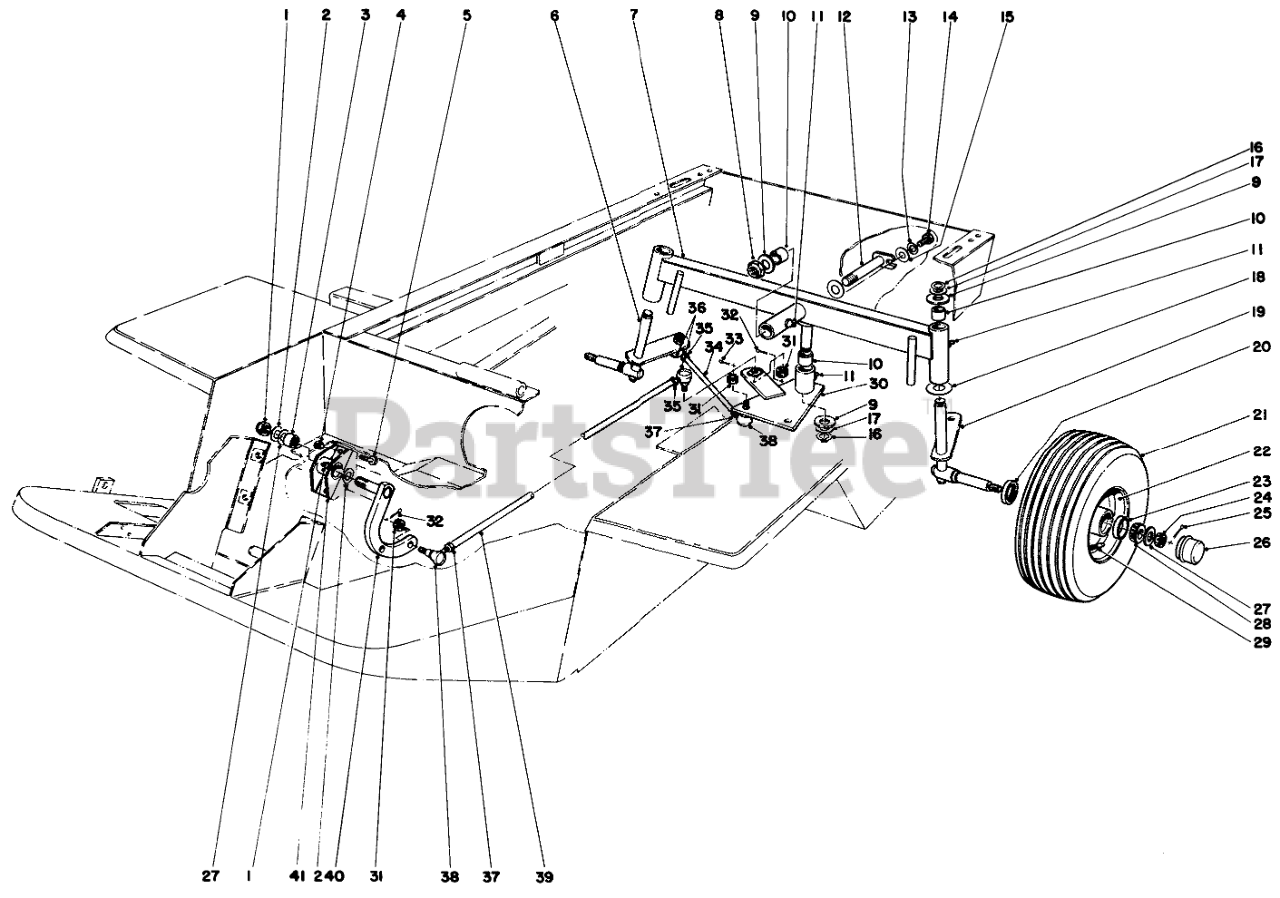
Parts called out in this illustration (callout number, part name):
1	NUT-LOCK, NI
2	THRUST WASHER
3	BEARING-NEEDLE
4	NUT-LOCK, NI
5	SCREW-HH
6	Spindle R.H.
7	Rear Axle (Incl. Ref. #10 & 11)
8	NUT-LOCK, NI
9	WASHER-THRUST
10	BUSHING
11	FITTING-GREASE
12	Pin-RearAxle
13	WASHER-LOCK
14	SCREW-HH
15	WASHER-FLAT
16	RING-RETAINING
17	WASHER
18	WASHER-THRUST
19	Spindle L.H.
21	TIRE 4 PLY
22	Rim (Incl. Ref.#23)
23	BEARING-CUP, TAPERED
24	NUT-HEX, SLOTTED
25	PIN-COTTER
26	CAP-DUST
27	WASHER-FLAT
28	BEARING-CONE, TAPERED
29	VALVE STEM AND CAP ASM
30	Steering Plate (Incl. Ref. #10 & 11)
31	NUT-SLOTTED
32	PIN-COTTER
33	PIN-COTTER
34	STRG TIE ROD R
35	NUT-HJ (LH THREAD)
36	Socket Assembly L.H. (Incl. Ref. #31)
37	NUT-JAM
38	Socket Assembly R.H. (Incl. Ref. #31)
39	REAR STRG TUBE PP
40	PIVOT ARM WA
41	Pivot Mount (Incl. Ref. #3 & 11)
